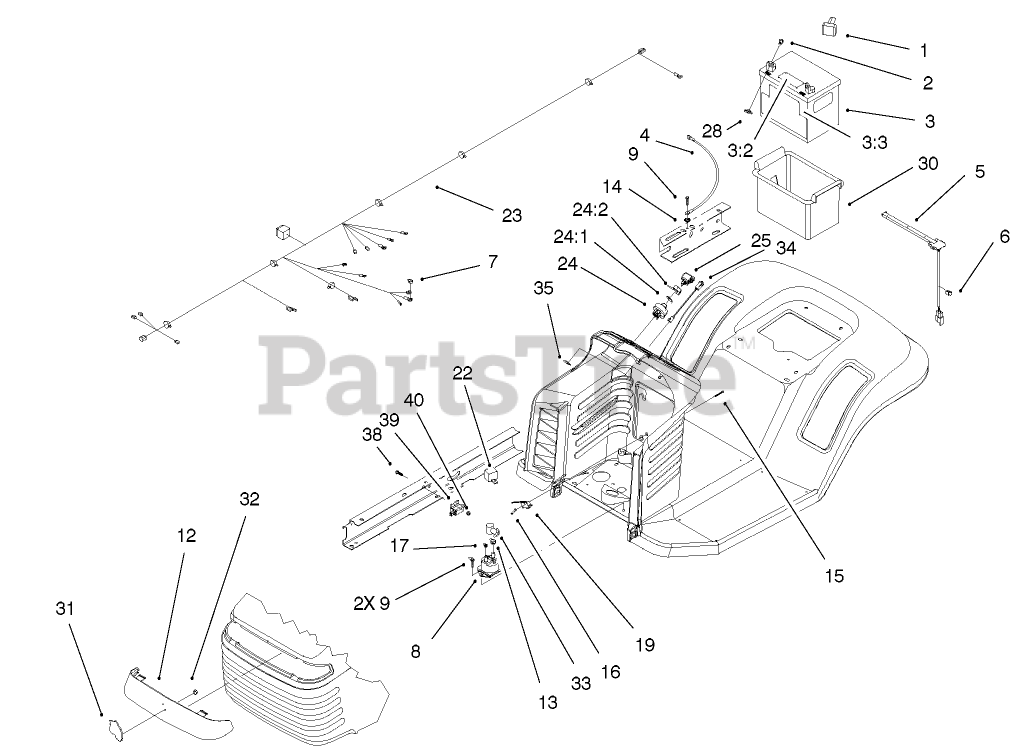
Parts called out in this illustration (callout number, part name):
1	BOOT-TERMINAL
2	SCREW-HH
3:2	Decal-Battery
3:3	Decal-Battery
4	WIRE ASM
5	SWITCH-SEAT
6	CLIP-RETAINER, WIRE
7	NUT-KEPS
8	SOLENOID
9	SCREW-HWH
12	LENS-HEADLIGHT
13	NUT-KEPS
14	WASHER-LOCK/EXT
15	SCREW-HH
16	NUT-SPEED
17	NUT-KEPS
19	SWITCH-MICRO
22	RELAY
23	HARNESS-WIRE, GEAR
24:1	WASHER-LOCK
24:2	NUT-HH
25	KEY-IGNITION
28	NUT-WING
30	BOX-BATTERY
33	BOOT-INSULATOR, TERMINAL
34	LIGHT-INDICATOR
38	SCREW-HSH
40	NUT-LOCK, NI
